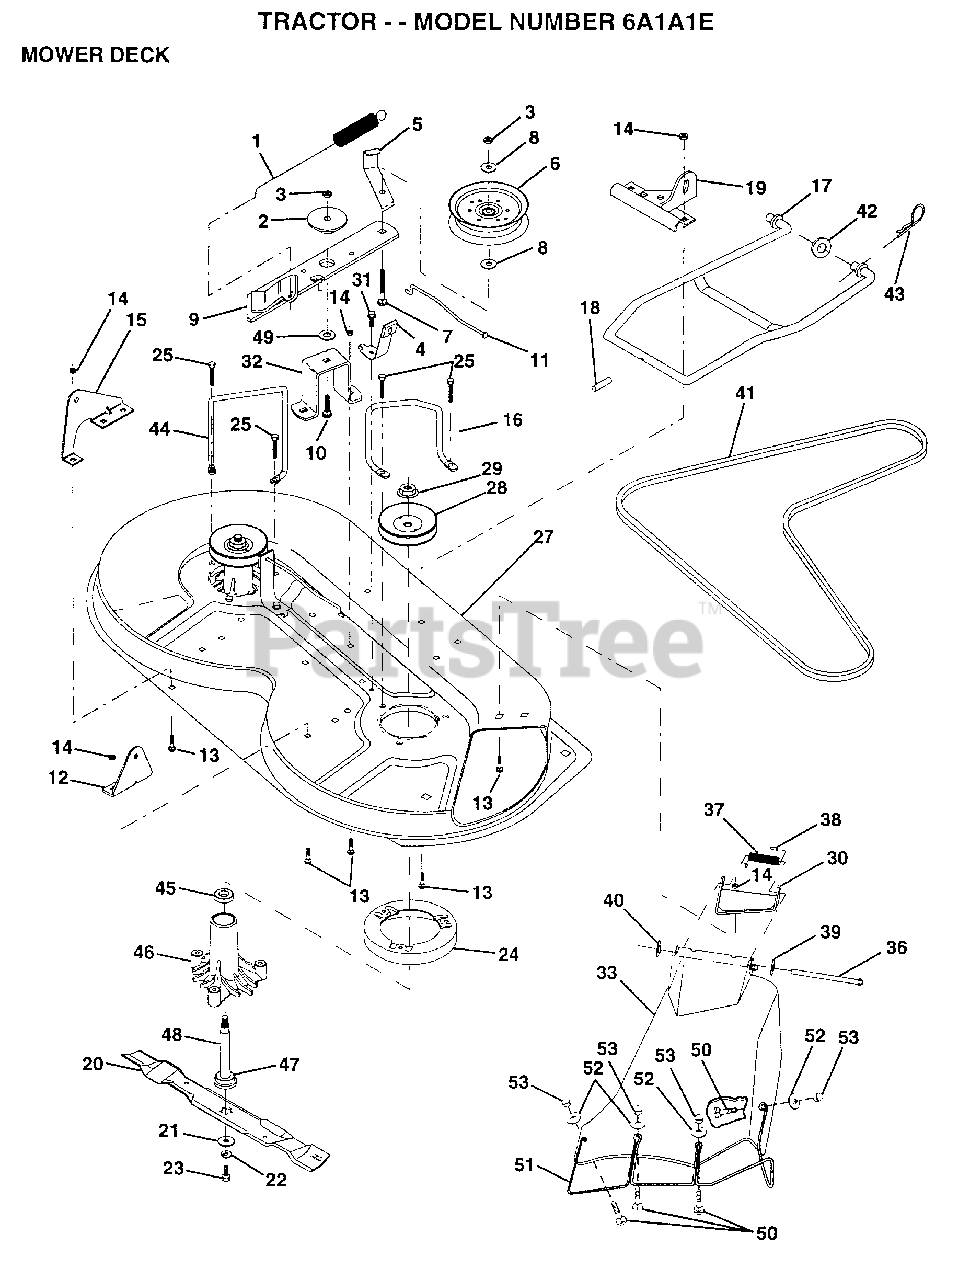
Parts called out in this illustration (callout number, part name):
1	SPRING CLUTCH MWR
2	SPACER RETAINER
4	BRAKE ASM
5	IDLER BELT GUIDE
6	PULLEY IDLER
7	BOLT
8	WASHER
10	BOLT.3/8-14X1.25
11	BRAKE ROD
12	"BRKT,LIFT REAR"
13	BOLT
15	"BRKT,LIFT REAR LH"
16	"KEEPER-BELT,RH"
17	MOWER LINK STAB
18	"PIN,GROOVE"
19	"BRKT,LINK STABILI"
20	"BLADE.36"" HIPERF"
21	WASHER.HARD.BLADE
23	BLADE BOLT
24	STRIPPER RND MWR
28	PULLEY, MANDREL
31	SCREW LT
32	"SUPT,IDLER ARM"
33	SHIELD.DEFL.36TUV
36	HINGE ROD
37	SPRING TORSION
38	CAP-SLEEVE LT
39	WASHER
40	NUT PUSH M
41	V-BELT.PRIM.78.5.
43	RETAINER.SPRING
44	KEEPER BELT LH
45	BEARING
46	HSG ASM MANDREL
47	BEARING.BALL
49	HARDENED WASHER
50	SCREW
51	GUARD.DFTR.MWR.36
53	ACORN NUT RB
